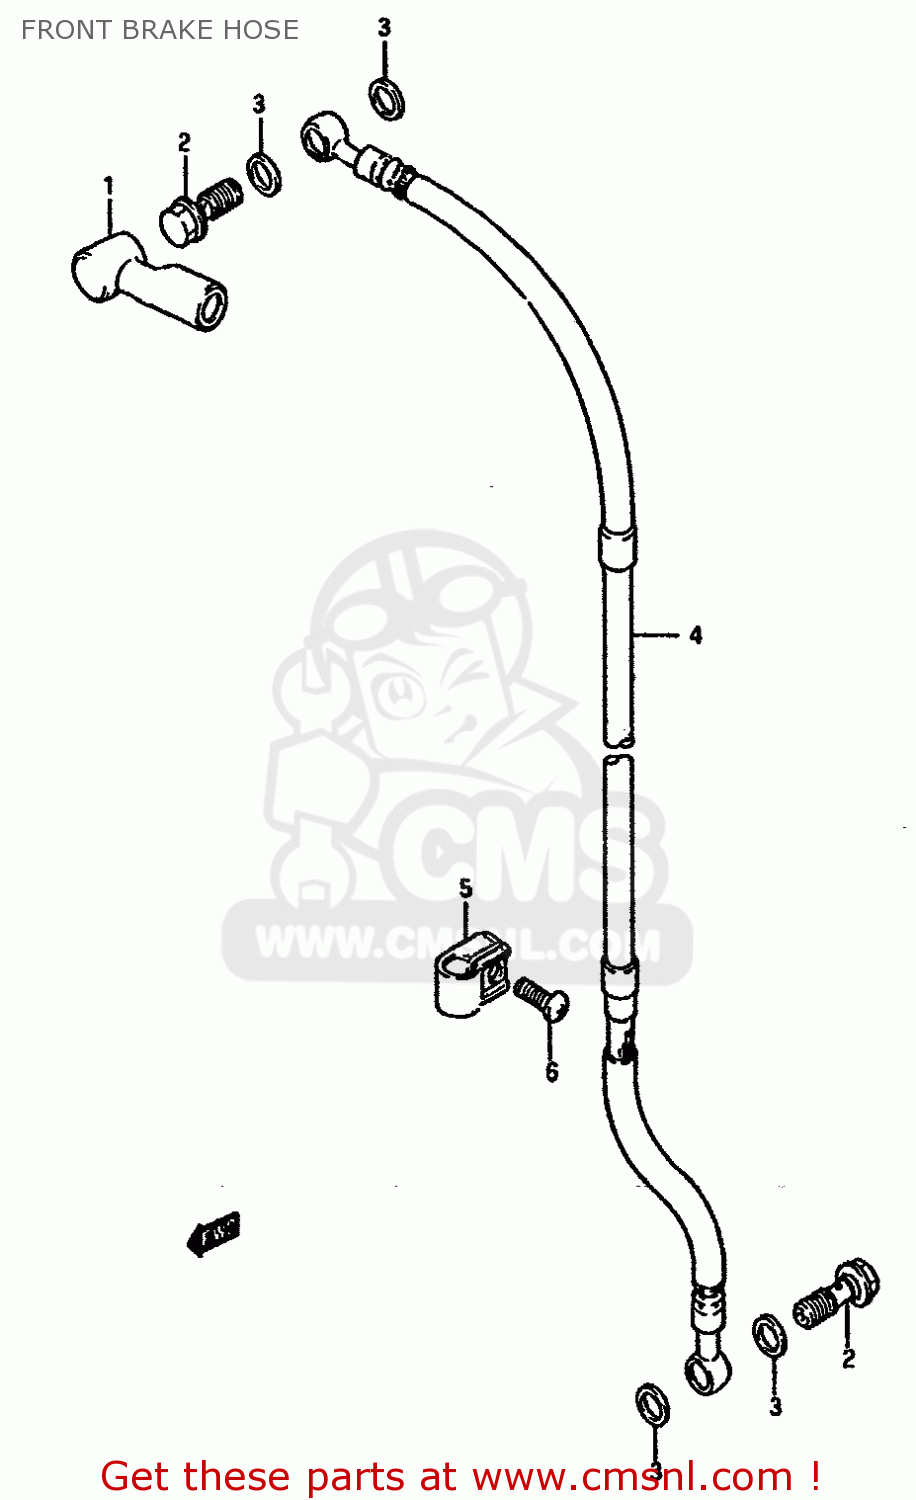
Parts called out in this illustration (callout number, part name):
1	BOOT,MASTER CYLINDER
2	BOLT UNION
3	WASHER(10X15X1.5)
4	HOSE,FRONT BRAKE
5	CLAMP,BRAKE HOSE
6	SCREW
